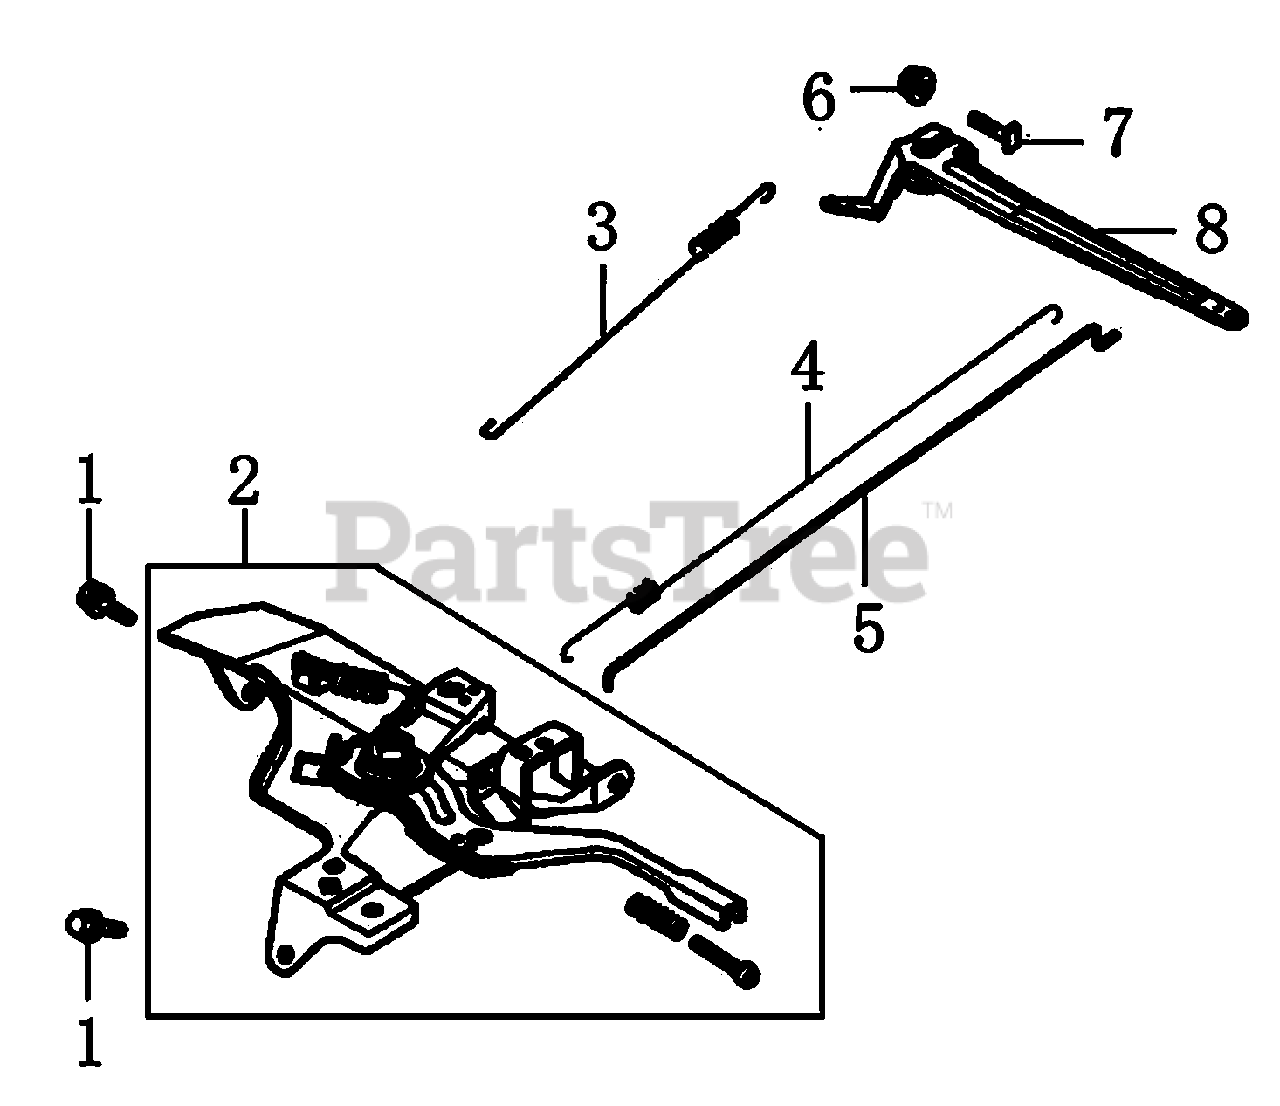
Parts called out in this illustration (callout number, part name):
1	NUT, FLANGE M6
2	CONTROL ASSY.
3	SPRING, CABLE RETURN
4	SPRING, THROTTLE RETURN
5	ROD, GOVERNOR
6	NUT, FLANGE M6
7	BOLT, QUADRATE HEAD
8	ARM, GOVERNOR
